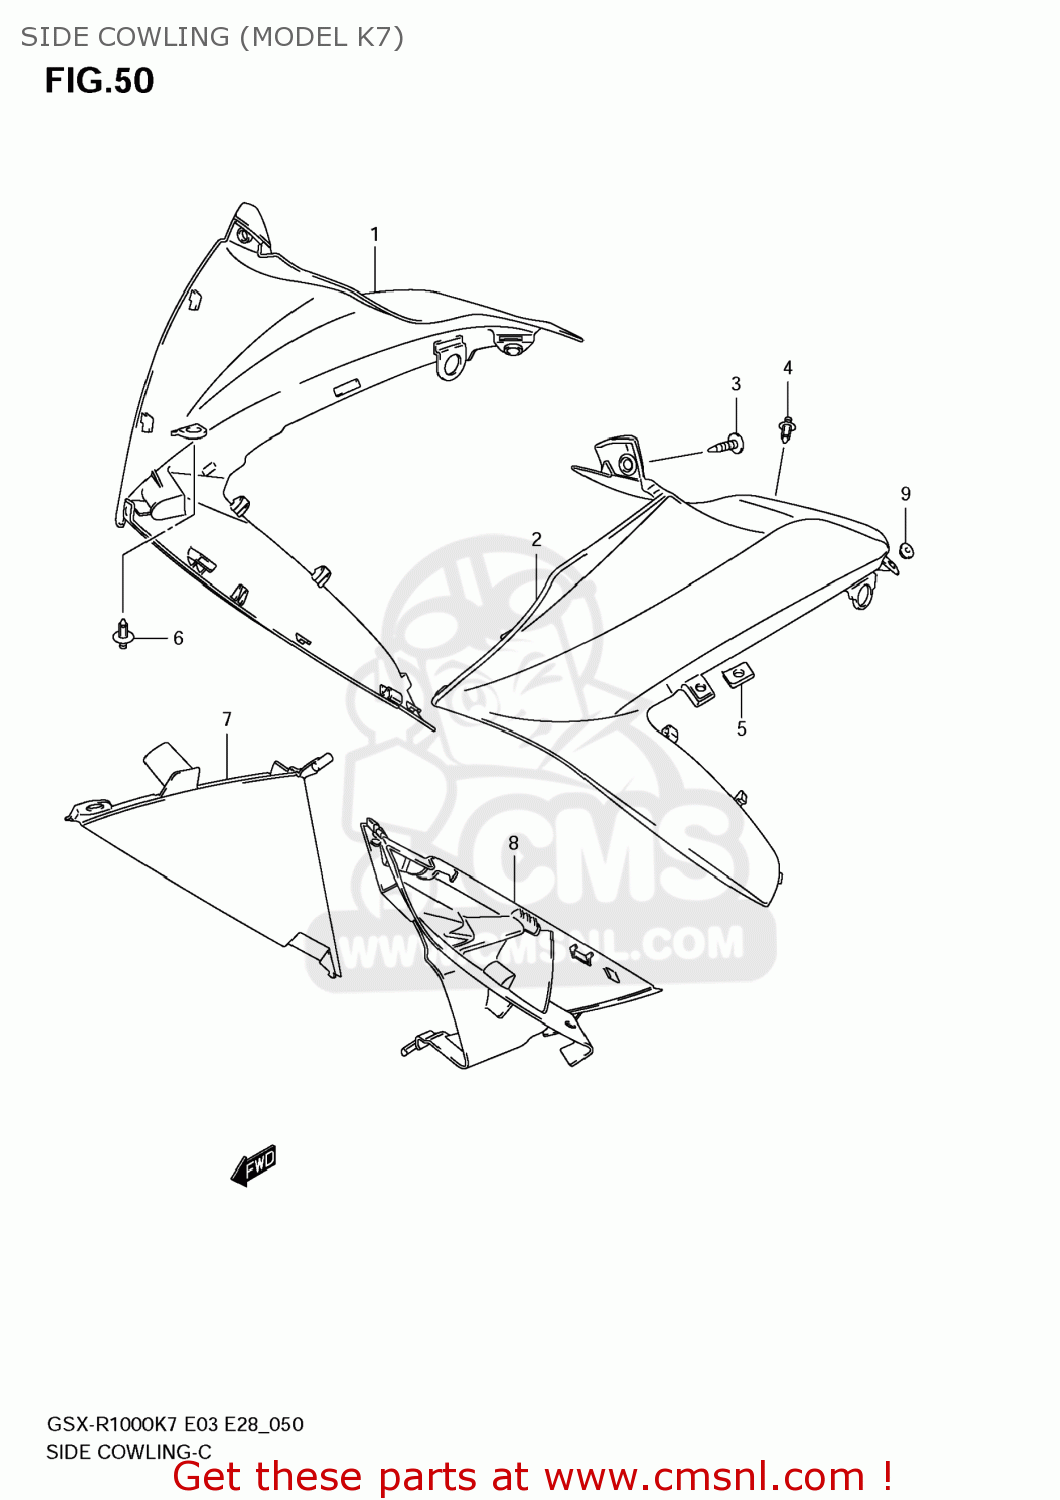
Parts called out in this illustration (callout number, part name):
1	COWLING,SIDE,R
2	COWLING,SIDE,L
3	SCREW(5X12)
4	CLIP
5	NUT
6	CLIP(BLACK)
7	COWLING,UNDER INNER,R
8	COWLING,UNDER INNER,L
9	CUSHION
